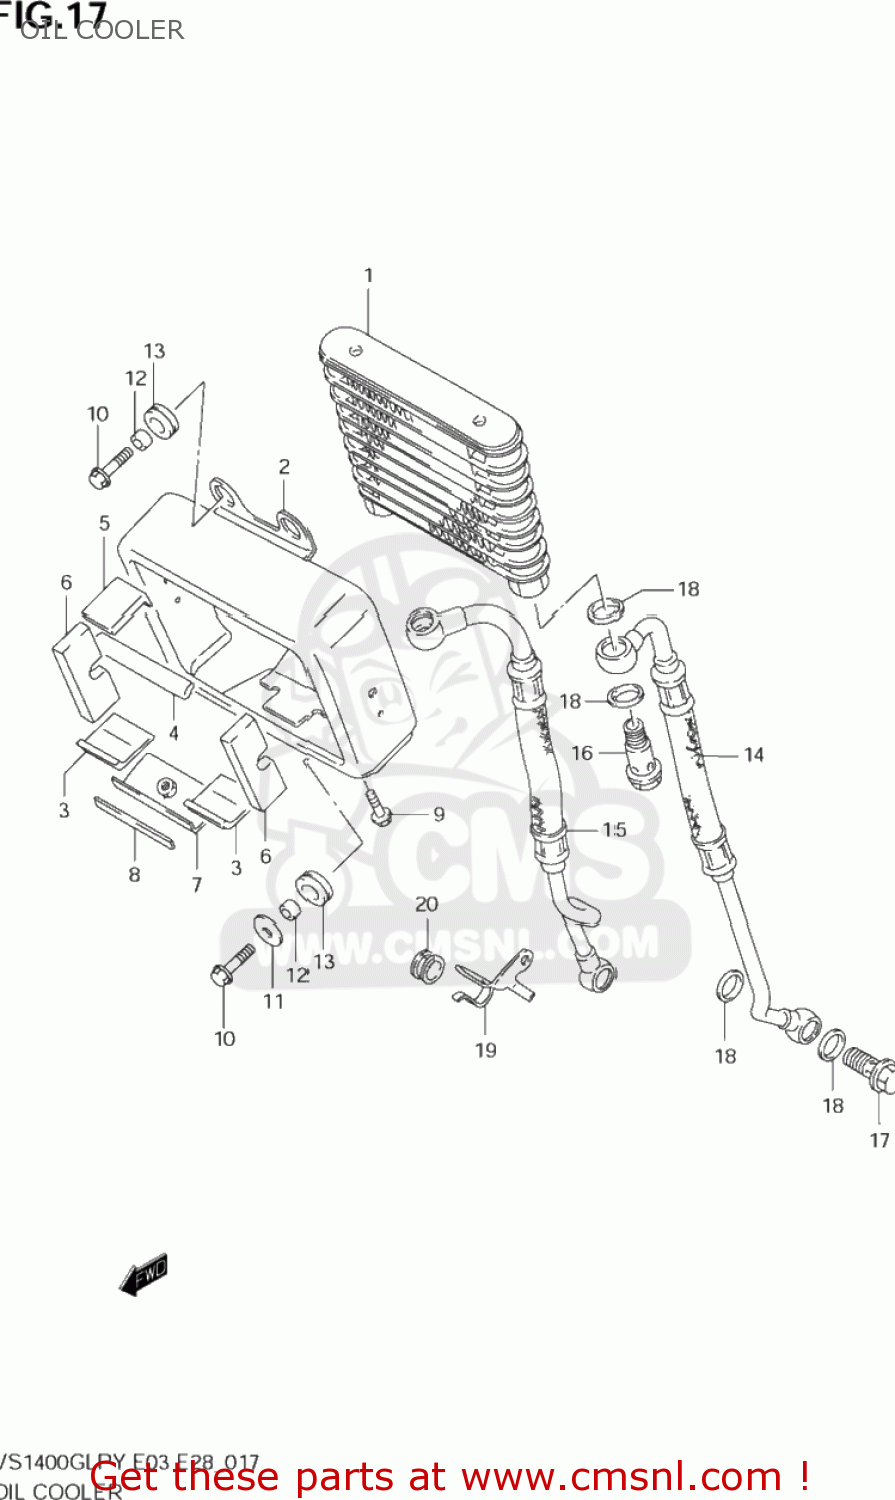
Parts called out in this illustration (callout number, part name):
1	COOLER ASSY,OIL
2	COVER,OIL COOLER
3	CUSHION,COOLER COVER LWR
4	CUSHION,CLLOER COVER UPR NO2
5	CUSHION,COOLER COVER UPR NO1
6	CUSHION,COOLER COVER SIDE
7	BRACKET,OIL COOLER
8	CUSHION,OIL COOLER BRACKET
9	BOLT
10	BOLT
11	WASHER(6.5X20X1.6)
12	SPACER(6.5X10X10)
13	CUSHION
14	HOSE,OIL COOLER,L
15	HOSE,OIL COOLER,R
16	BOLT UNION
17	BOLT UNION
18	GASKET(14X20X1.5) (NAS)
19	CLAMP,OIL COOLER HOSE,R
20	CUSHION
